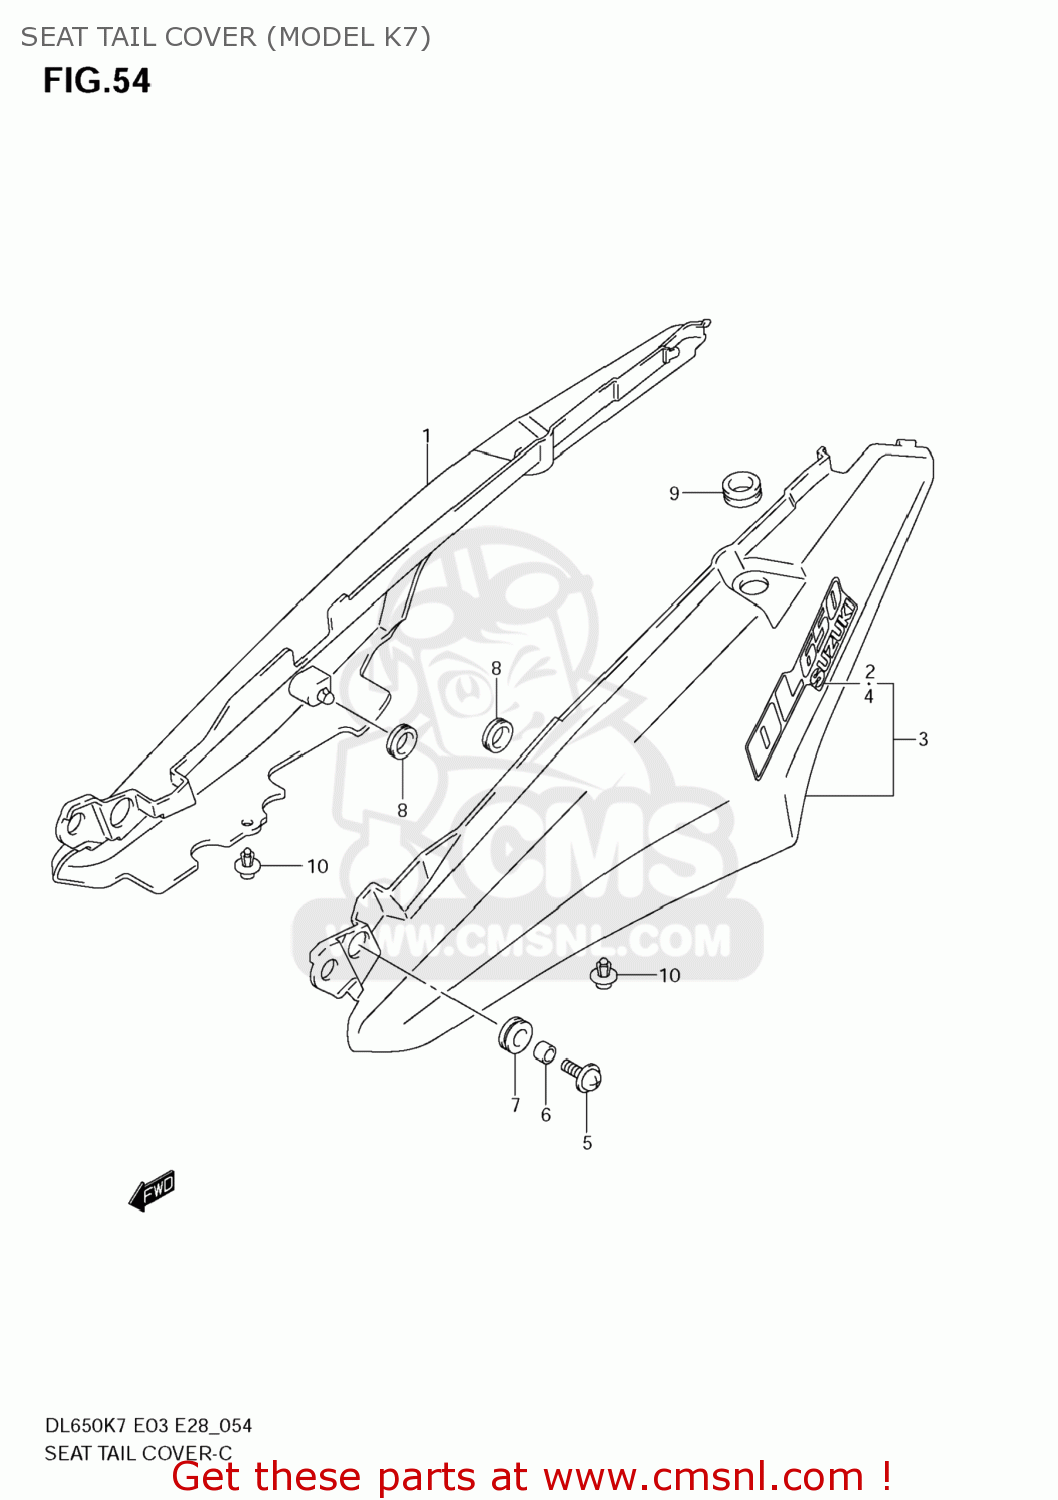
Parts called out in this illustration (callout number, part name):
1	COVER,SEAT TAIL,R(RED)
2	EMBLEM,SEAT TAIL COVER
3	COVER,SEAT TAIL,L(RED)
4	EMBLEM,SEAT TAIL COVER
5	SCREW(6X20)
6	SPACER(6.5X12X9)
7	CUSHION
8	CUSHION
9	CUSHION
10	CLIP(BLACK)
